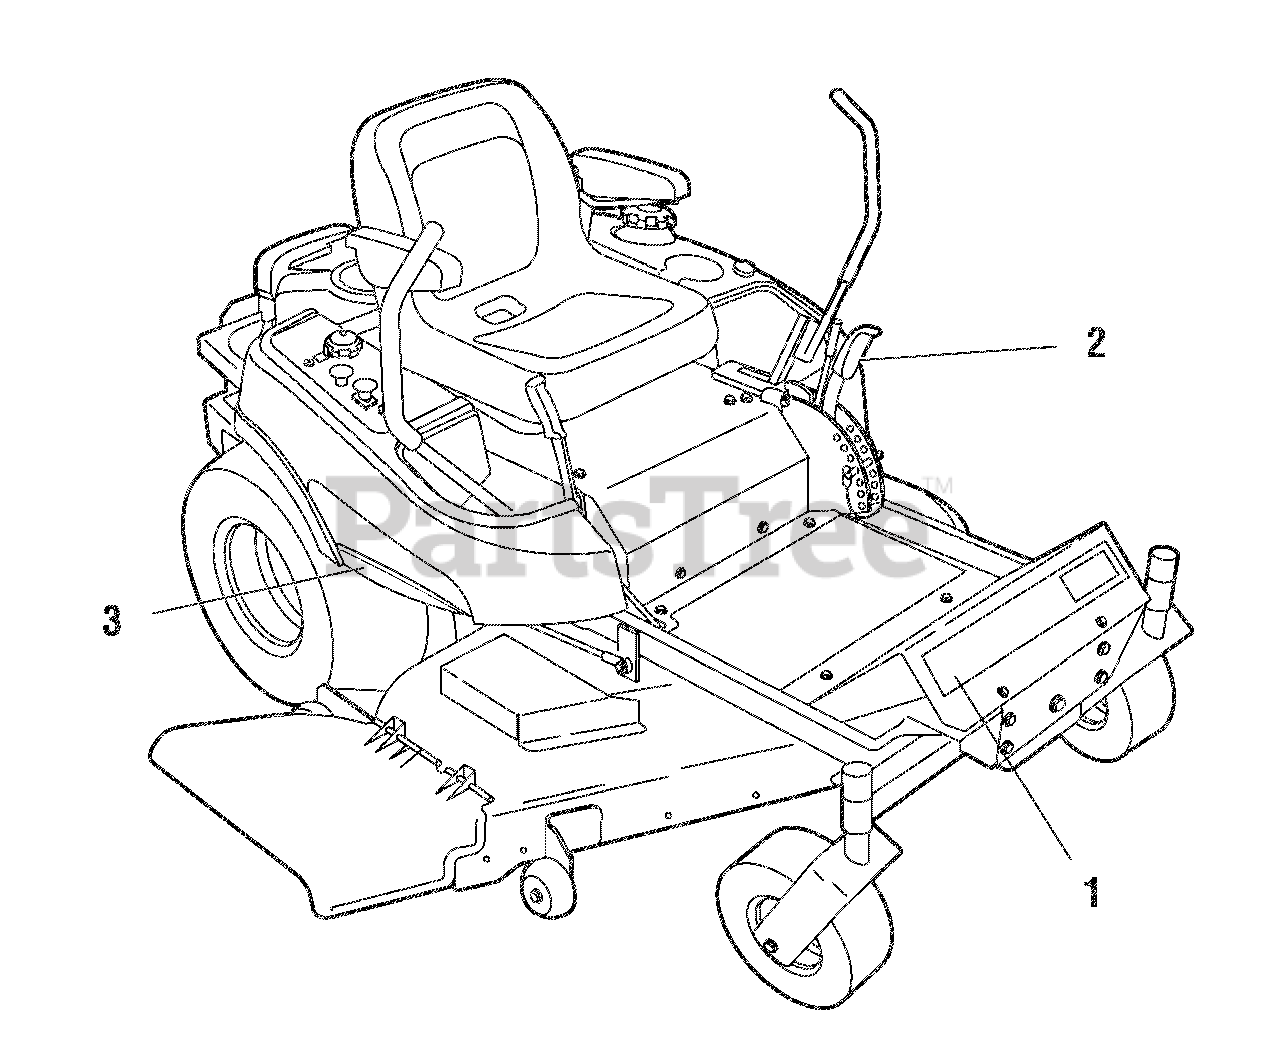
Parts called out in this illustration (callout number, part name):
1	DECAL, SNAPPER, SILVER & BLACK, 8.5"
2	DECAL, STRIPE, LH, SNAPPER
3	DECAL, STRIPE, RH, SNAPPER
